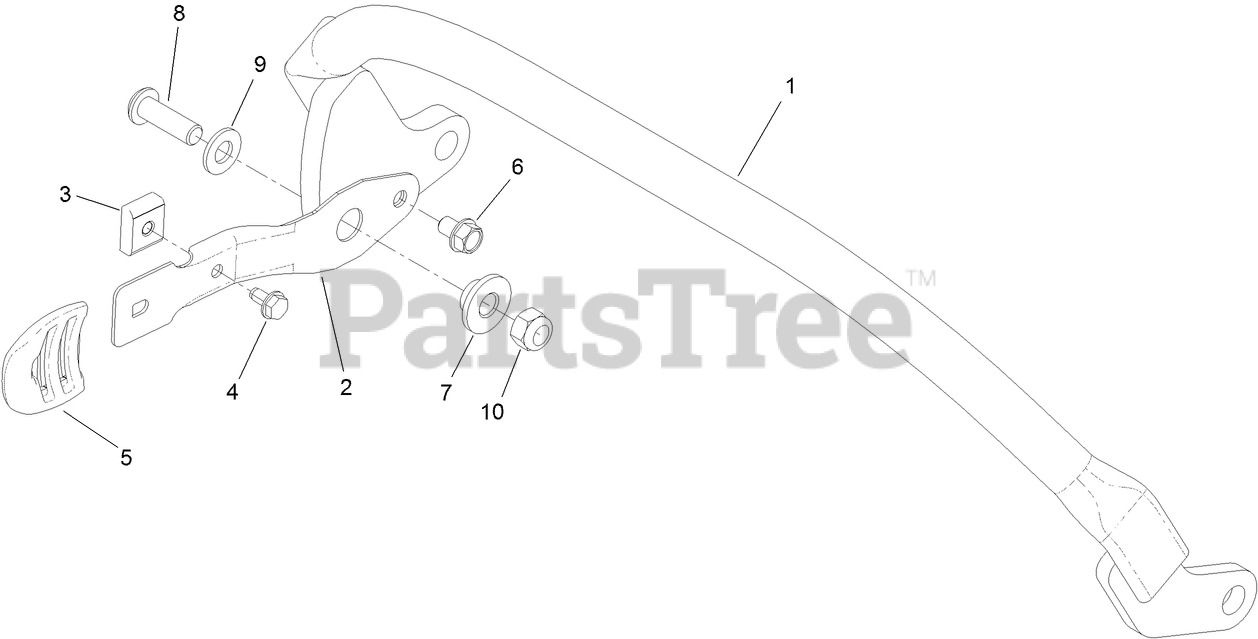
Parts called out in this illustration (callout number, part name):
1	REFERENCE BAR
2	ARM-SPRING
3	KEY-ARM, SPRING
4	SCREW-HWH
5	KNOB-LEVER, HOC
6	SCREW-HWH
7	WASHER-STEPPED, BAFFLE
8	SCREW-HSBH
9	WASHER-PLAIN
10	NUT-LOCK, NI
